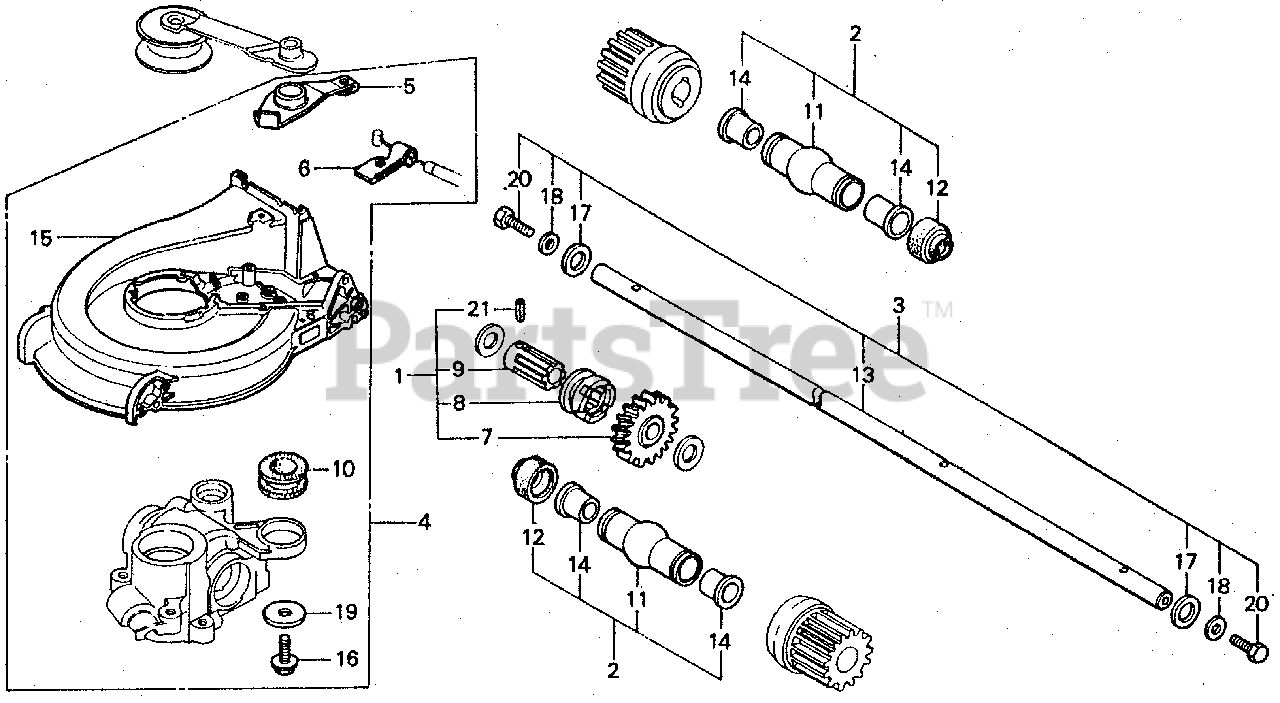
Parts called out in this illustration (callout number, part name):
4	HOUSING KIT, CUTTER *NH2M* (METALLIC SILVER) (NOT AVAILABLE)
5	ARM, CHANGE
6	HOLD, CHANGE WIRE
10	MOUNT, RUBBER
15	HOUSING, CUTTER *NH2M* (METALLIC SILVER)
16	BOLT, FLANGE (6X12) (CT200)
19	WASHER, SEAT
20	BOLT, HEX. (6X12)
